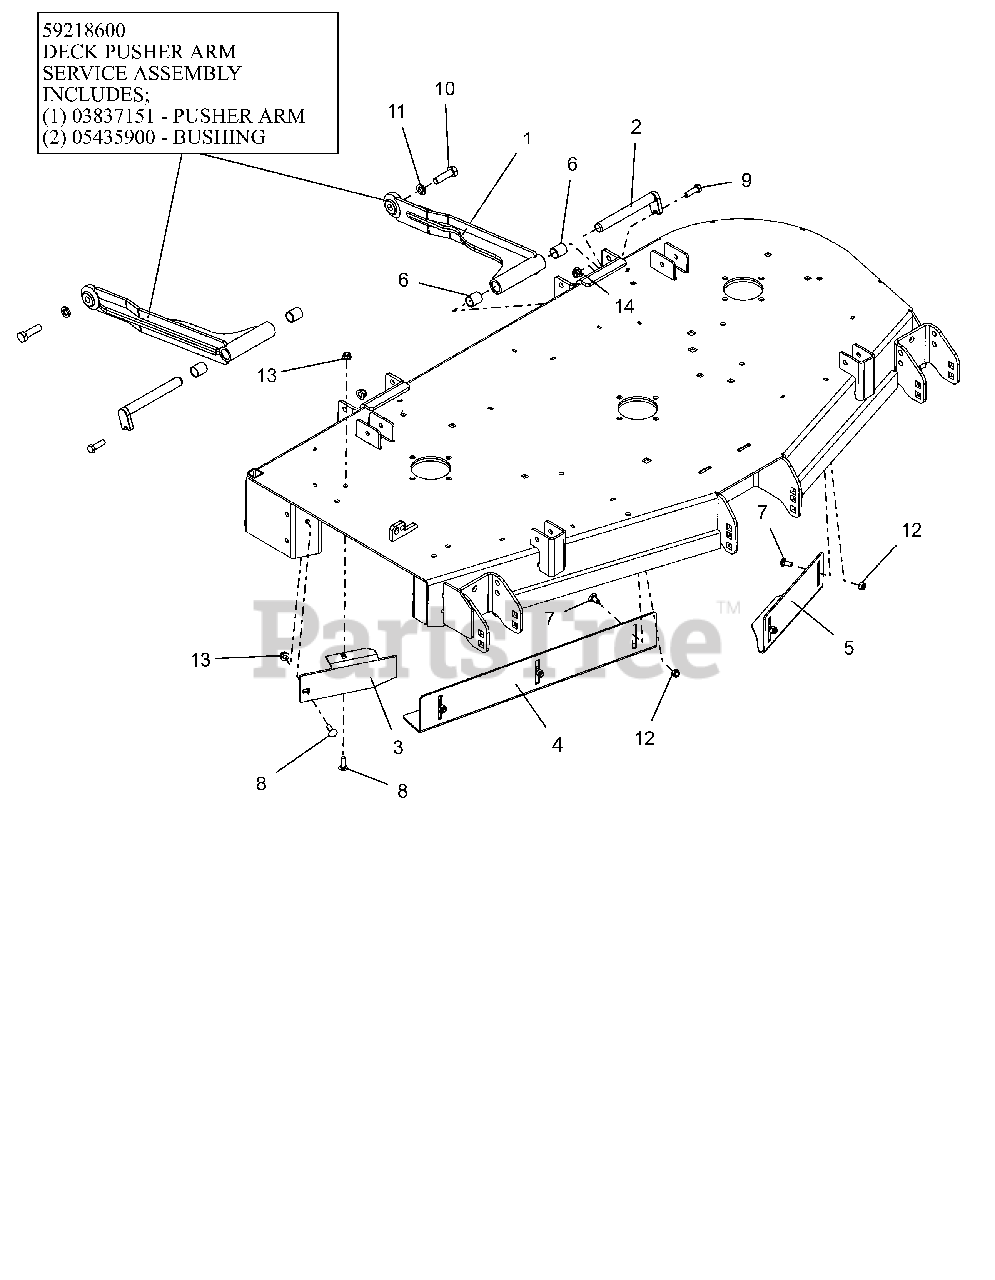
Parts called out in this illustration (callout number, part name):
1	DECK STABILIZER ARM - BLACK
1	DECK STABILIZER ARM W/BUSHINGS
2	PIN, MOWER MTG
3	52" DISCHARGE BAFFLE - RED
4	52" RH VACCUM BAFFLE - RED
5	52" LH VACUUM BAFFLE - RED
6	BRG, .750 X .875 X 1.000
7	@BLT-RDHDSQNK .31-18X.75 G5YZ
8	@BLT-RDHDSQNK .31-18X1.00 G5YZ
9	@BLT-HEX .38-16X1.25 GR5 YWZC
10	BLT-HEX .50-13X1.75 GR5EP80 YZ
11	@WSHR-LK .50X.125 REG YWZC
12	@NUT-LK-NYL .312-18 YWZC
13	@NUT-LK-NYL-FLG .31-18 YWZC
14	@NUT-LK-NYL-FLG .38-16 YWZC
